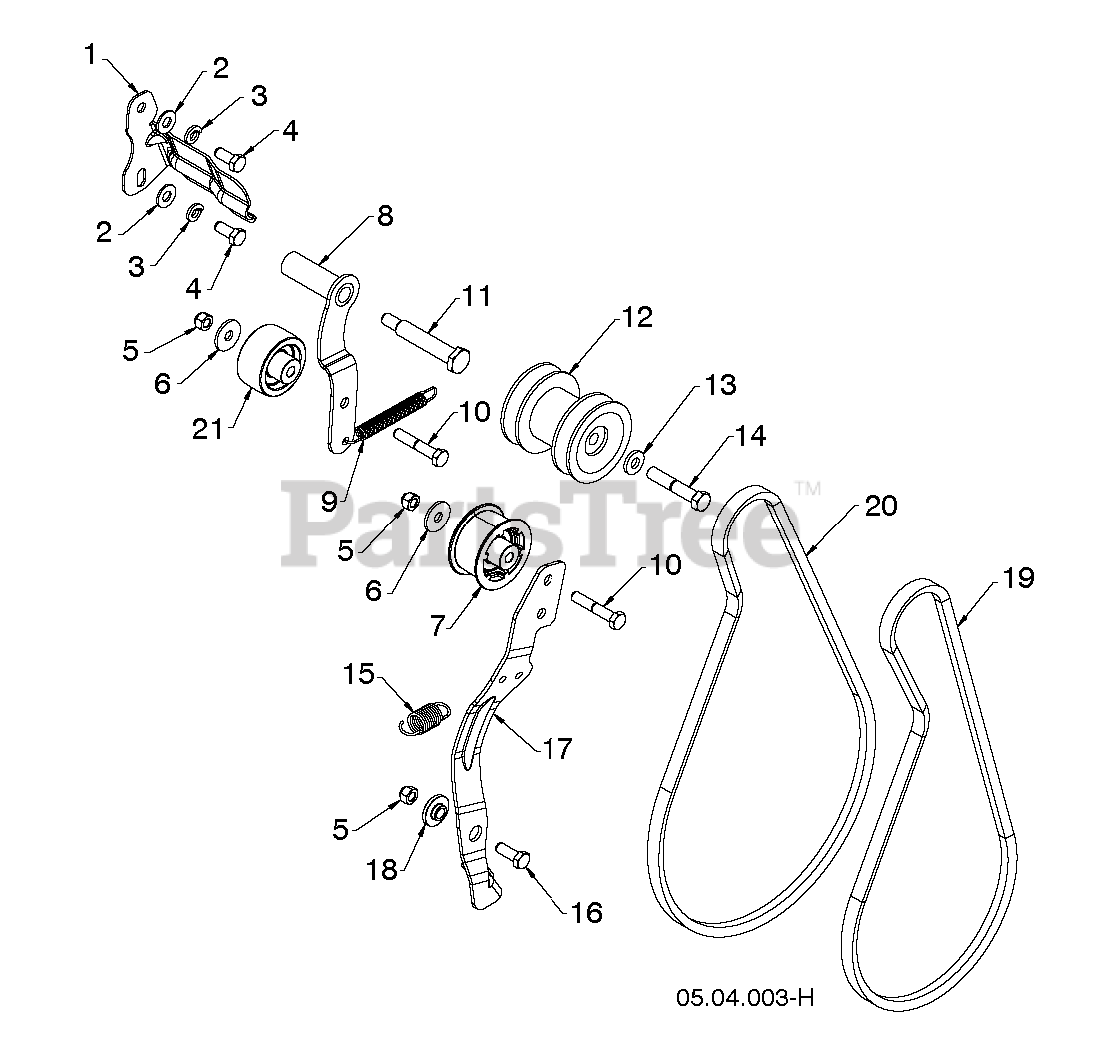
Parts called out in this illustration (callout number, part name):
1	BRACKET.BELT.KEEPER.004.BZP
2	WASHER M
3	WASHER.LOCK.HVY.HLCL.SPR.5/16
4	SCREW 5/16-24 X .75 GR5
5	NUT.71038.31-18.HEX.NYLOCK
6	STEEL WASHER
7	PULLEY,IDLER,2.00 W SPA
8	ARM IDLER DRIVE WELDMENT_HOT
9	SPRING RETURN IDLER ARM
10	BOLT, HEX 5/16-18X1-3/4
11	BOLT 5/16-24X2.25 HEX HEAD SHO
12	RP PULLEY.ASM.IMPELLER/DRIVE
14	BOLT.HD.HEAD.3/8-24X2.50 (2 2)
15	SPRING RETURN, IDLER ARM, IMPE
16	BOLT
17	BRACKET ARM.IDLER.IMPELLER ARM
18	RP BUSHING, IDLER PIVOT
19	BELT.AUGER.HI-CRANK
20	RP_BELT.DRIVE.HI-CRANK
21	PULLEY.IDLER.FLANG.2.O/SPACER
